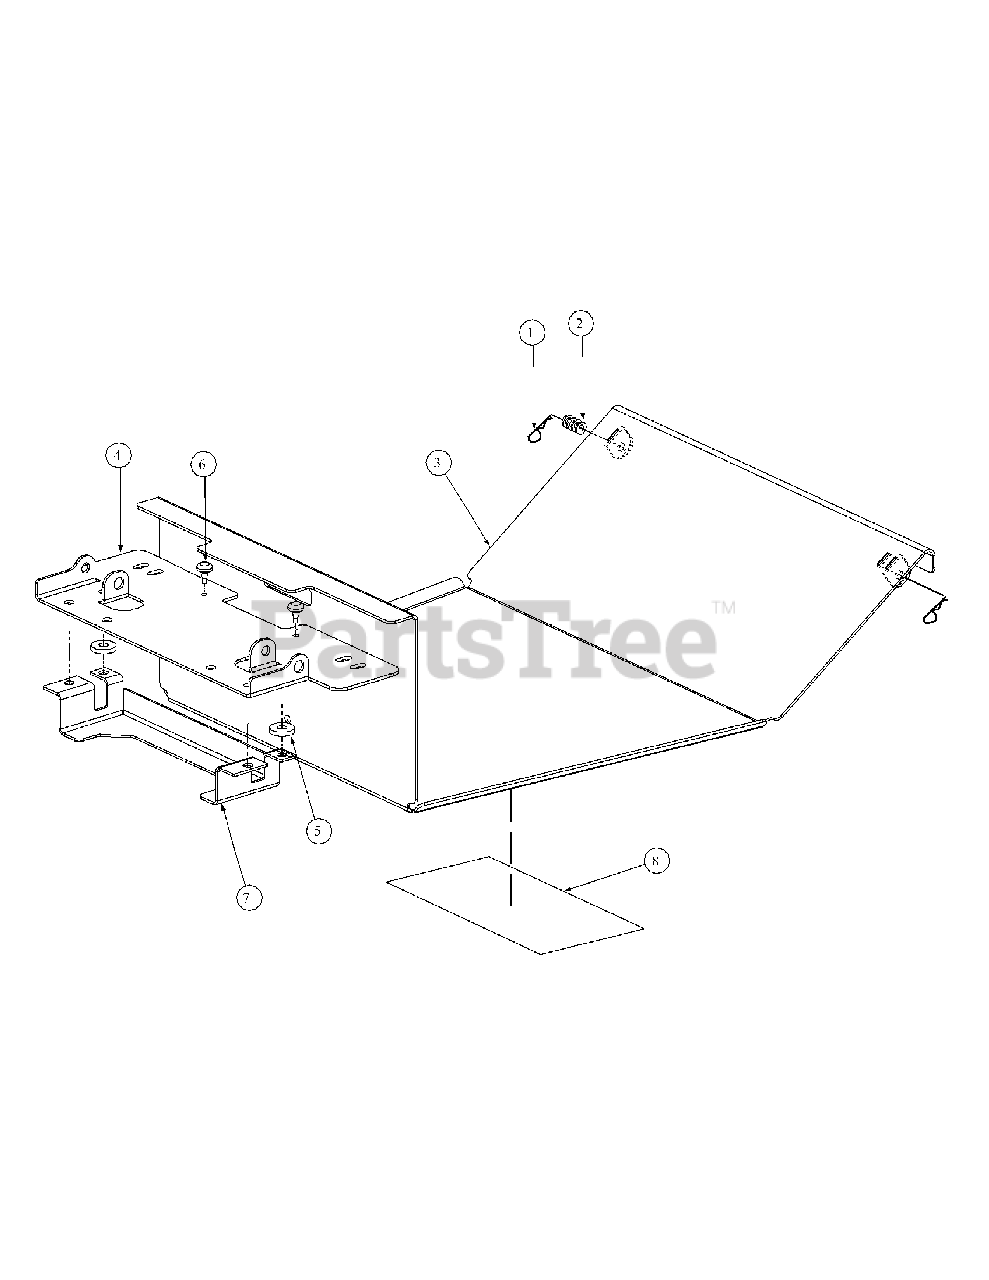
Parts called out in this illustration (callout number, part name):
1	Hair Pin, 3/8-1/2
3	Floor Panel Assembly
4	Panel Seat
5	Washer
6	Rubber Bumper, .62 OD x .22 Thick
7	Support, Seat Bracket
8	Label, Belt Routing and Lubrication
